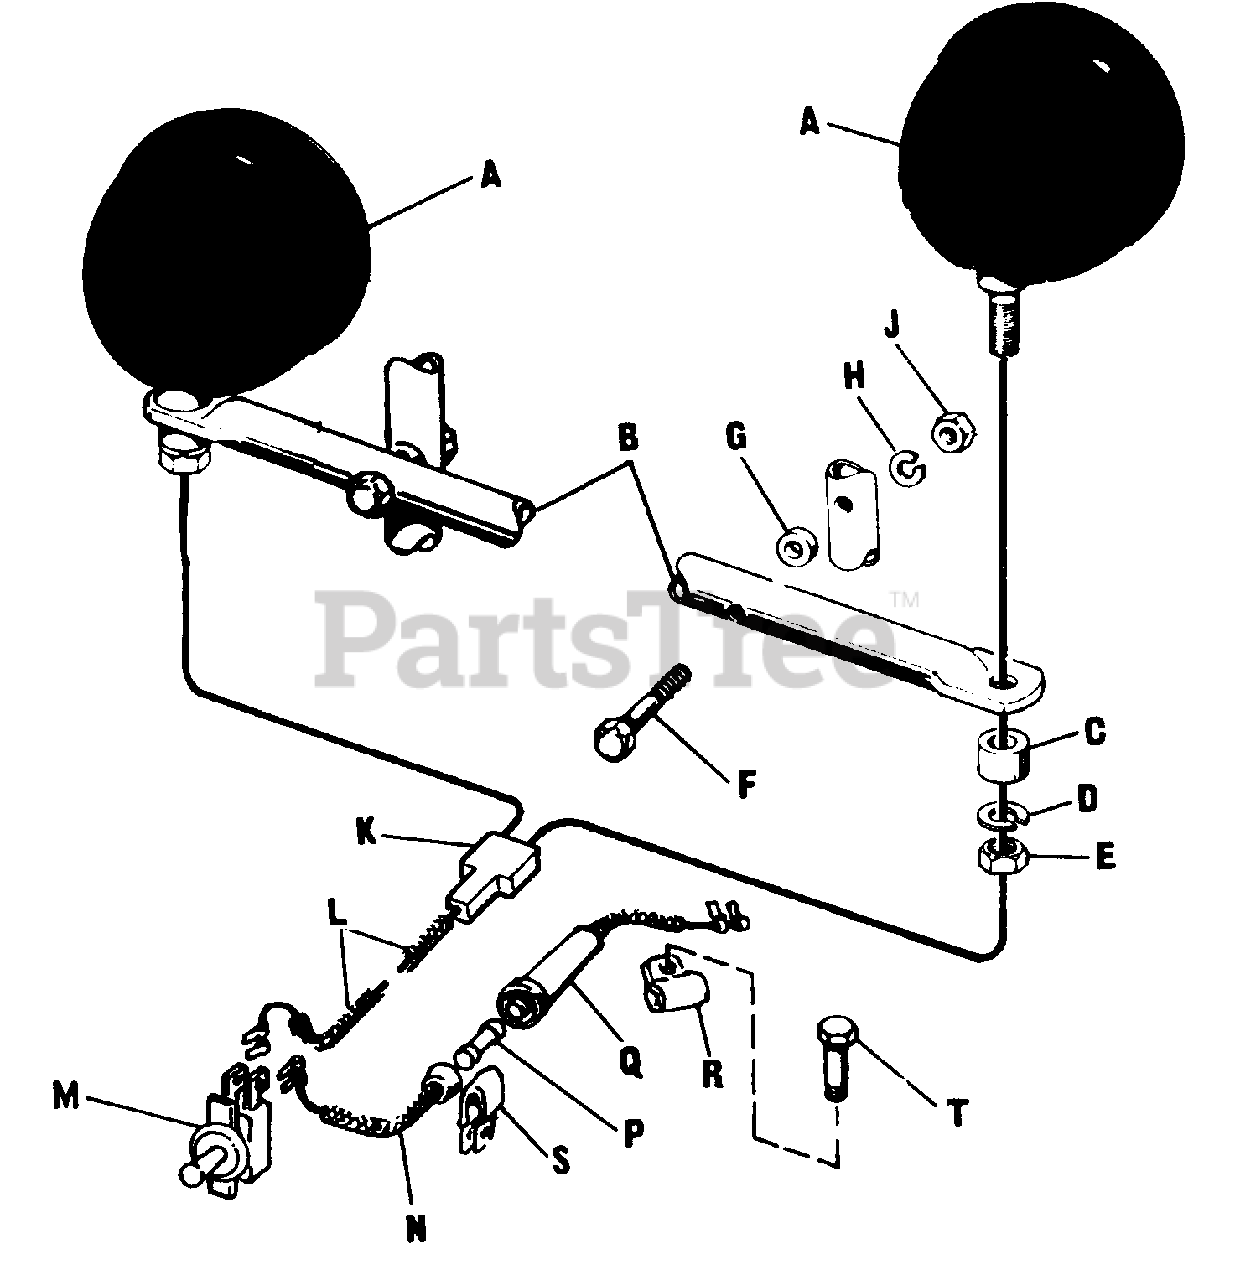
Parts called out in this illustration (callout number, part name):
A	Lamp Assembly
B	Light Support
D	Lock Washer, 1/2"
E	Full Hex. Nut, 1/2"-13
F	Hex. Cap Screw, 5/16"-18 x 2-1/2"
H	Lock Washer, 5/16"
J	Full Hex. Nut, 5/16"-18
K	Insulated Connector
L	Wire (switch to lamp) 32"
M	Toggle Switch (with hardware)
N	Wire (fuse to switch) 26"
P	Fuse 20 Amp.
Q	Wire (fuse to voltage reg.) 2-1/2"
R	Clamp, front
S	Clamp, side
T	Hex. Cap Screw, 1/4"-20 x 5/8"
